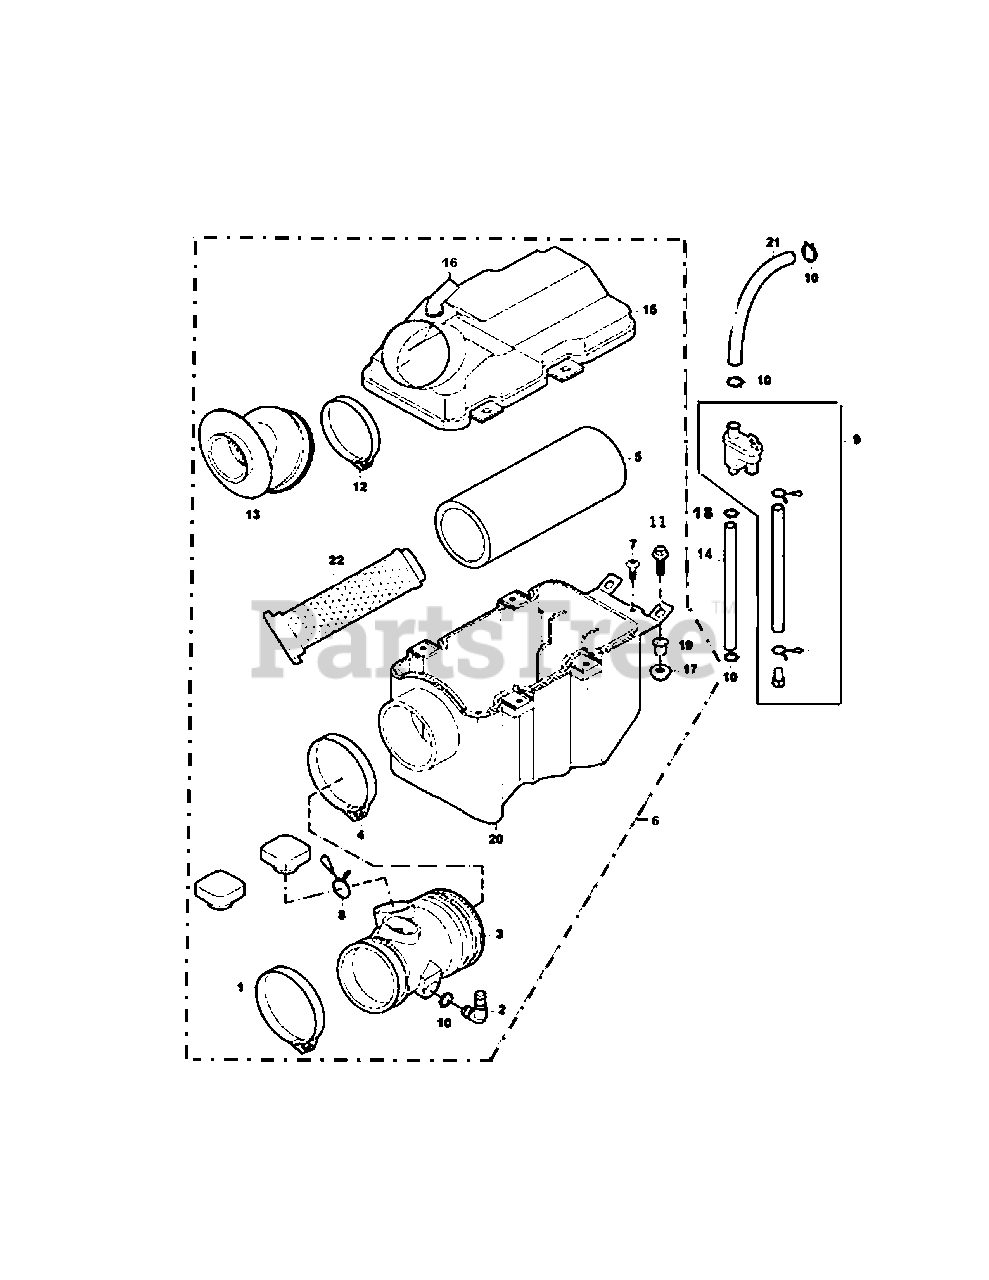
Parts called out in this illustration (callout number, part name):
1	Screw Hoop60-80
2	Rubber Pipe III 11x15x50-50
3	Air-Out Pipe
4	Clamp IV
5	Air Filter Element
6	Air Filter Assembly
7	Cross Recessed Plate Head Screw M5x12
9	Oil & Air Separator
11	Hexagon Flange Bolt M6x20
12	Clamp IV
13	Primary Air Filter Outlet Pipe
14	EGR Tube 011x015x100
15	Air Filter Cover
17	Hexagon Flange Nut M6
18	Steel Clip 12
19	Bushing 6.5x9x22x6.5
20	Air Filter Shell
21	Rubber Pipe 11x15x140-90
22	Air Filter Element
23	Block, Used Oil Pipe
24	Hexagon Flange Bolt M6x20
